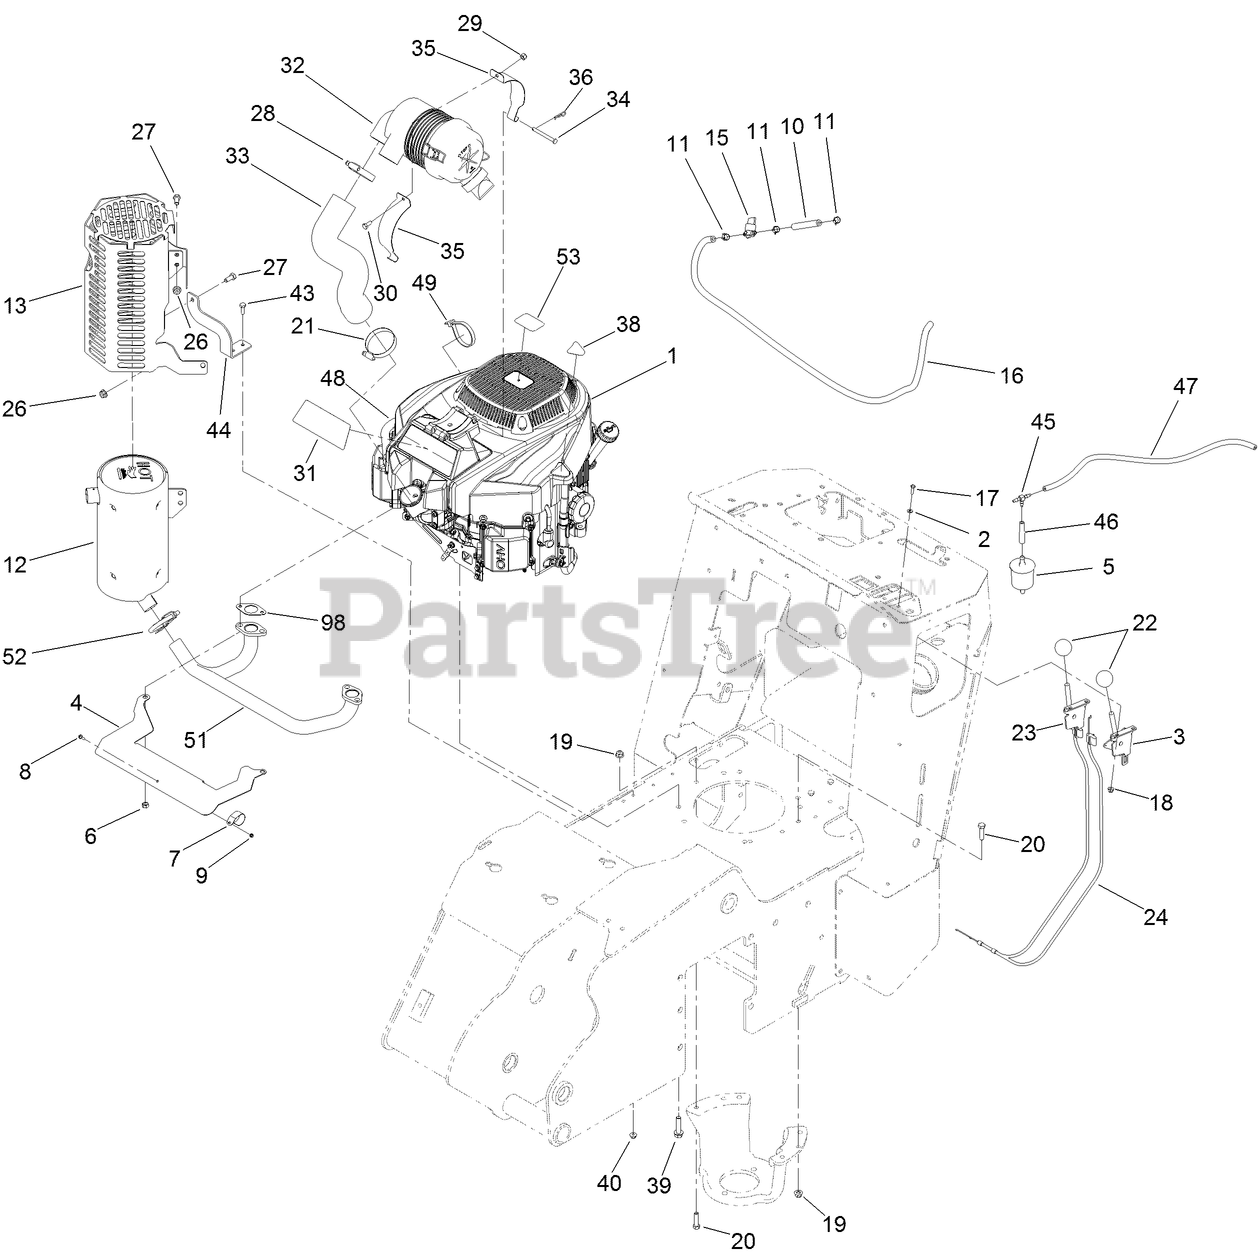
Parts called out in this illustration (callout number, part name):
1	ENGINE-2P77F-HD
2	WASHER-FLAT
3	LEVER-CONTROL
4	PLATE-SHIELD, HEAT
5	FILTER-FUEL
8	SCREW-PAN
9	NUT-HEX
10	HOSE-FUEL
11	CLAMP-HOSE
12	MUFFLER
13	GUARD-MUFFLER
15	VALVE-FUEL
16	HOSE-FUEL
18	NUT-HF
19	NUT-HF, NI
20	SCREW-HH
21	CLAMP-HOSE
23	LEVER-CONTROL
24	CABLE-CONTROL
26	NUT-FLANGE
27	SCREW-HH
28	CLAMP-HOSE
29	NUT-HEX
30	SCREW-HH
31	DECAL-AIR CANISTER MOUNT
32	AIR CLEANER ASM
33	HOSE-INTAKE
34	PIN-CLEVIS
35	STRAP-CANISTER, AIR
36	PIN-COTTER
38	DECAL-DRAIN, OIL
39	SCREW-HWH
40	NUT-HF
43	SCREW-HH
44	BRACKET-MUFFLER GUARD
45	FITTING-TEE
46	HOSE-FUEL, MOLDED
47	HOSE-FUEL
48	SLEEVE-THERMAL
49	TIE-CABLE
51	MANIFOLD
52	CLAMP-MUFFLER
98	GASKET-EXHAUST
